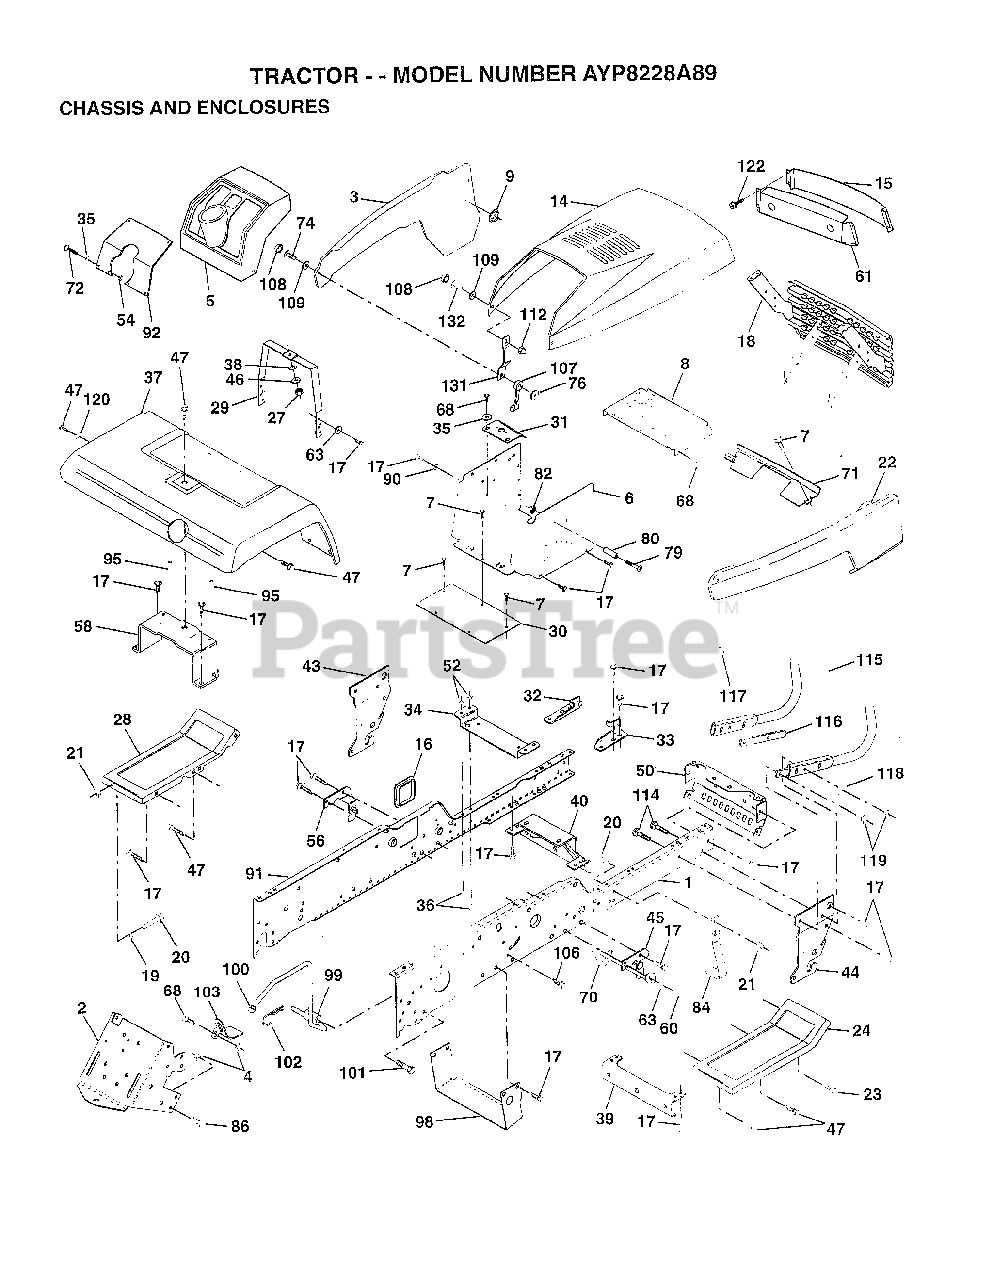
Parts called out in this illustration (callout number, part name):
1	"RAIL,FRAME RH"
2	DRAWBAR GT
3	"PANEL,ASM SIDE LH"
4	NUT.7/16
5	DASHBOARD BLACK
6	DASH LOWER
7	SCREW
8	SUPPORT.DASH.BTRY
9	PAL NUT LT
14	"HOOD ASM.,PNT"
15	LENS.BAR.CLEAR
16	COVER ACCESS
17	SCREW
19	WASHER
20	BOLT
22	PANEL ASM.SIDE RH
23	SCREW GTV
24	FOOTREST.RH.LT/GT
28	FOOTREST.LT.LT/GT
29	DASH.SUPT.YP/HUSQ
30	SADDLE.HYDRO.95
31	BRKT SUPT 1-PC VG
32	BRACKET ASM FRAME
33	BRACKET ASM FRAME
34	BRACKET.ENG.SUPT.
35	WASHER
36	BOLT
38	LOCKWASHER
39	BRACKET.AXLE.FRT.
40	"BRKT SUPPORT,AXLE"
43	BRACKET.SUS.FT.LH
44	BRACKET.SUS.FT.RH
45	BRACKET ASM., SUSP CHASSIS RH
46	WASHER PM
47	SCREW LT
50	"BRKT CHASSIS,FRNT"
56	BRACKET ASM., SUSP CHASSIS LH
58	BRKT.ASM.FENDER
60	SCREW
61	BEZEL.ASM.
63	WASHER
68	SCREW LT
70	GUIDE.BELT.MID.SP
72	SCREW
74	SCREW
76	WELDNUT
79	SCREW
80	SPACER LT
84	STOP.OVER.CENTER
86	BOLT
90	LOCKWASHER
91	"RAIL FRAME,LH"
92	"PLATE DASH,SLKSCR"
95	NUT-PUSH YT
98	BRACKET SKID CHAS
99	ROD BYPASS
101	SCREW LT
102	RETAINER M
103	LOCK BYPASS BRKT
107	HOOD LATCH T
108	SNAP CAP LT
109	WASHER LT
112	ACORN NUT RB
114	BOLT.3/8-14X1.25
115	BUMPER.ASM
116	BRACKET.EXT.BUMP.
117	PLUG.PLASTIC
118	WASHER
120	WASHER HYT
122	SCREW.HEX.WS.HD
131	BKT.SPT.HOOD/PANL
132	SCREW.10-24X3/8.
